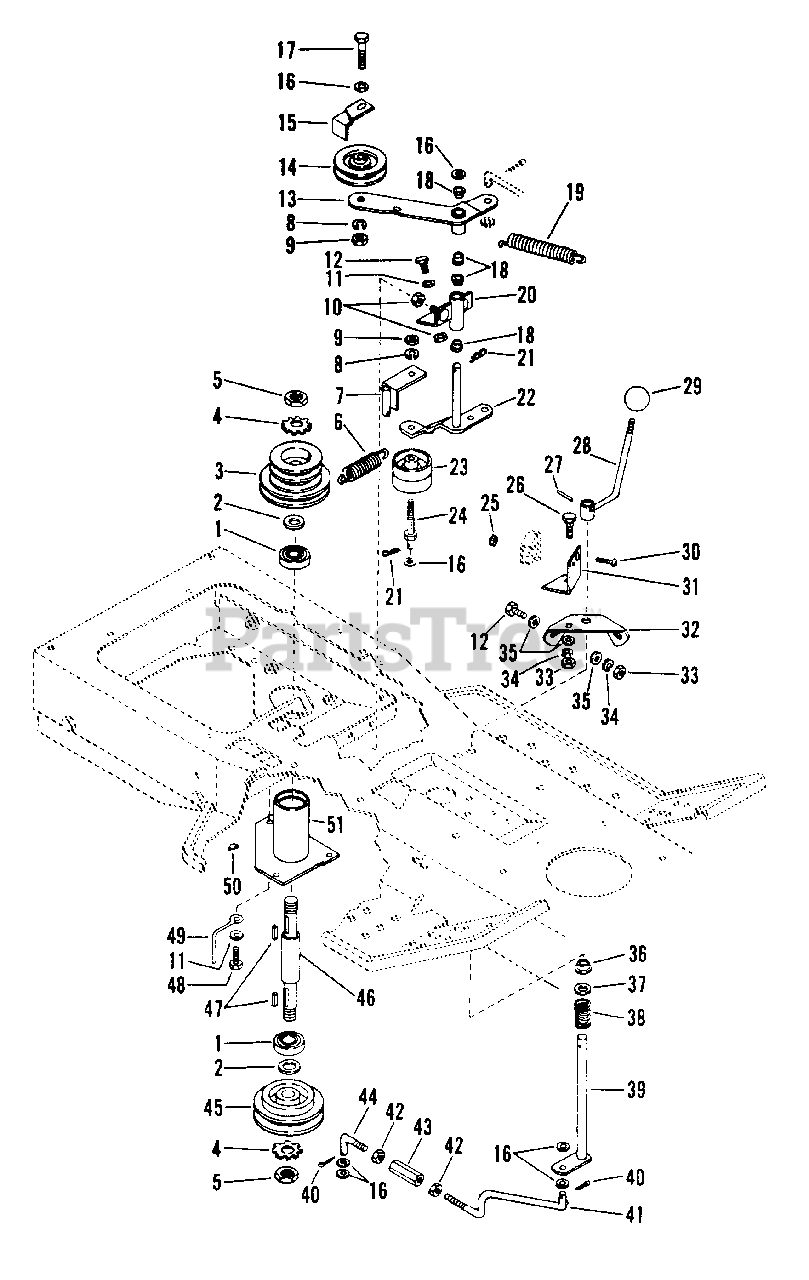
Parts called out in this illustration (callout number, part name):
1	BEARING, RADIAL
2	WASHER, FLAT .812X1.496X.134
3	SHEAVE, DOUBLE GROOVE
4	LOCKWASHER, INTERNAL 3/4
5	NUT, JAM 3/4-10 HEX
6	SPRING, DRIVE
7	BRACKET
8	WASHER, LOCK 3/8 REG.
9	NUT, HEX 3/8-16
10	NUT, LOCK 5/16-18
11	WASHER, FLAT .312X.734X.065
12	BOLT, HEX 5/16-18X.75
13	ARM, IDLER
14	IDLER, MAIN
15	RETAINER, BELT
16	WASHER, FLAT .406X.812X.065
17	BOLT, HEX 3/8-16X1.75
18	BUSHING, FLANGE
19	SPRING, EXTENSION
20	PIVOT, IDLER
21	HAIRPIN, INTERNAL 3/32
22	ARM, IDLER
23	IDLER, ATTACHMENT
24	BOLT, IDLER MOUNTING
24	BOLT, HEX 3/8-16X1.75
25	NUT, KEPS 10-24
26	BOLT, CARRIAGE 5/16-18X.75
27	PIN, SPRING .187X1.250
28	HANDLE, PTO
29	KNOB, ADJUSTMENT CONTROL
30	SCREW, MACHINE 10-24X1.00 RHD
31	BRACKET, SWITCH
32	BRACKET
33	NUT, HEX 5/16-18
34	WASHER, LOCK 5/16 SP
35	WASHER, FLAT .312X.734X.065
36	BUSHING, FLANGE
37	WASHER, LOCK 5/16 SP
38	SPRING, COMPRESSION
39	LEVER, PTO
40	PIN, COTTER .125X1.00
41	LINK, IDLER
42	NUT, JAM 3/8-16 HEX
43	NUT, COUPLING 3/8-16
44	LINK, IDLER ADJUSTER
45	SHEAVE, JACKSHAFT
46	SHAFT
47	KEY, STRAIGHT SAE 1035
48	BOLT, HEX 5/16-18X1.00
49	FINGER, BELT
50	FITTING, ZERK
51	HOUSING, SPINDLE
